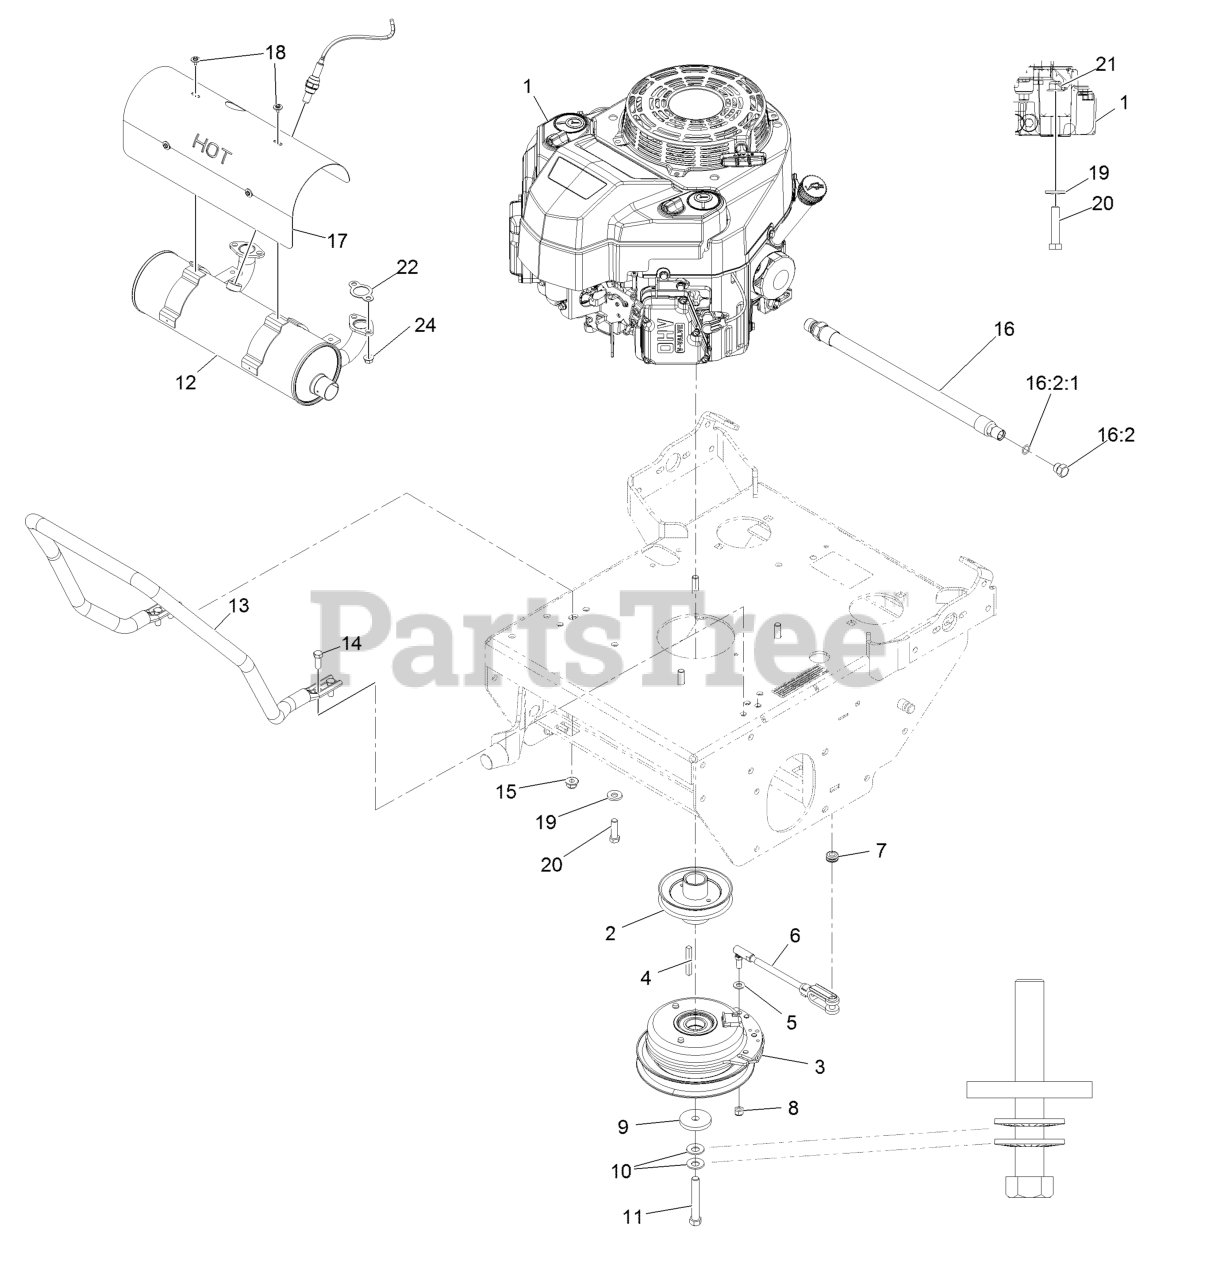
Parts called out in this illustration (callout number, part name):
2	Sheave, W/ Hub
3	Clutch, 125 Ft/Lbs, 1.13
4	Key-Machine 1/4 X 1/4 X 2
5	Washer-5/16 SAE
6	ASM, Clutch Anchor
7	Grommet
8	Nut-Lock 5/16-24
9	Washer-Clutch
10	Washer-Spring Disc 7/16
11	Screw-HH 7/16-20 X 3
12	Muffler-Ttx, Efi
13	Guard,Air Cleaner
14	Screw-HH 3/8-16 X 1
15	Nut-Nyloc 3/8-16 Flg
16	Oil Drain Hose ASM
16:2	Plug-W/O-Ring
16:2:1	O-Ring
17	Shield-Muffler,Ttx Efi
18	Screw-HH, Thread Forming
19	Washer-Spring Disc 5/16
20	Screw-HH 5/16-18 X 1 1/2
21	Nut-Nyloc 5/16-18 Flg
22	Gasket-Exhaust
24	Nut-Flange
